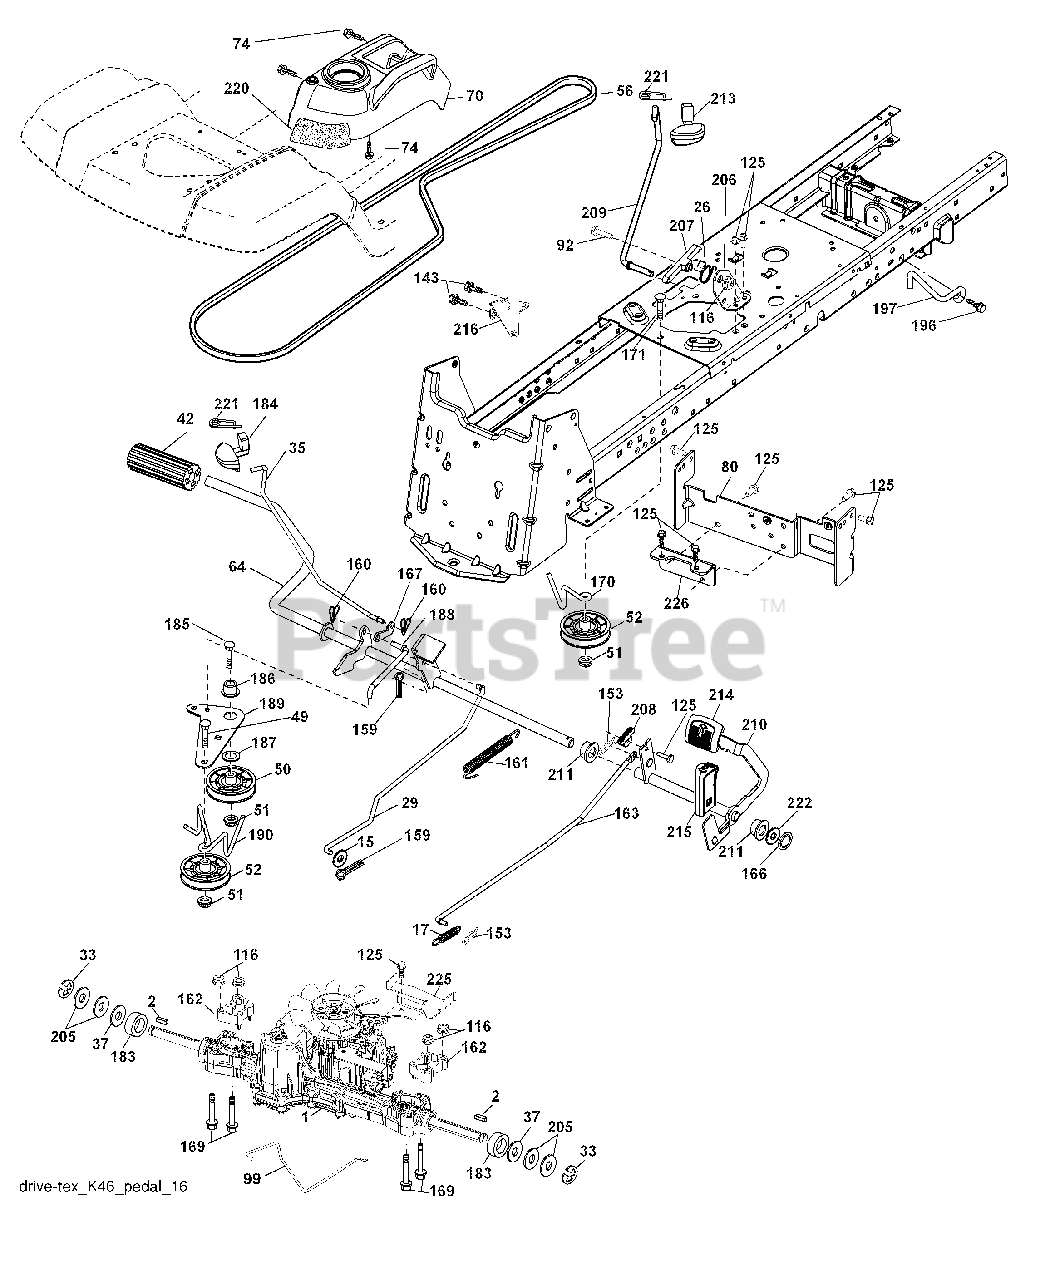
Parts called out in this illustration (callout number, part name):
1	Transaxle, TUFFTORQ K46 BT
2	Key 1/4 x 2.5
15	Washer 13/32 x 13/16 x 16 Ga.
17	Spring, Brake
26	Spring Return Cruise
29	Rod, Brake
35	Rod, Brake, Park
37	Washer Harden
42	Cover, Foot Pedal
50	Pulley Idler Flat
51	Lock Nut 3/8-16
52	Idler V-Groove 910" Offset
56	V-Belt, Drive
64	Shaft Asm. Pedal Brake Control
70	Console Asm.
74	Screw 1/4 x 1/2
80	Strap Torque
92	Bolt Fin Hex 5/16-18 unc x 1.25
99	Rod Spring Bypass
116	Nut Lock Hex Flange 5/16-18
125	Screw 5/16-18 x 3/4
143	Screw Thdrol 5/16-18 x 1/2
153	Retainer Spring
159	Pin Cotter 1/8 x 3/4
160	Retainer Clip
161	Spring, Return, Clutch
162	Spacer Transaxle
163	Rod Pedal Control
166	Nut Push .625
167	Latch Brake Parking
169	Bolt Hex Flghd 5/16-18 x 3.75
170	Keeper Belt Centerspan
171	Bolt RDHD SQNK 3/8-16 unc x 2
183	Spacer Split
184	Handle Parking Brake
185	Bolt Rdhd Sqnk 3/8-16 x 2-1/2
186	Spacer Retainer
187	Washer
188	Link Clutch Ground Drive
189	Bellcrank Ground Drive
190	Keeper Bellcrank Ground Drive
196	Screw 3/8-16 x 1
197	Bracket Clutch Anti-Rotation
206	Bracket Mount Latch Cruise
207	Latch Control Cruise
208	Gear Sector Control Cruise
209	Rod Control Cruise
210	Rocker Asm. Pedal Control
211	Bearing Nylon
213	Knob Control Cruise
214	Pedal Forward
215	Pedal Reverse
216	Bracket Pulley Idler
220	Reflector RH
221	Retainer Spring Clip Handle
222	Washer 21/32 x 1-1/4 x 10 Ga.
225	Keeper Belt Trans.
226	Bracket Mount Torque
